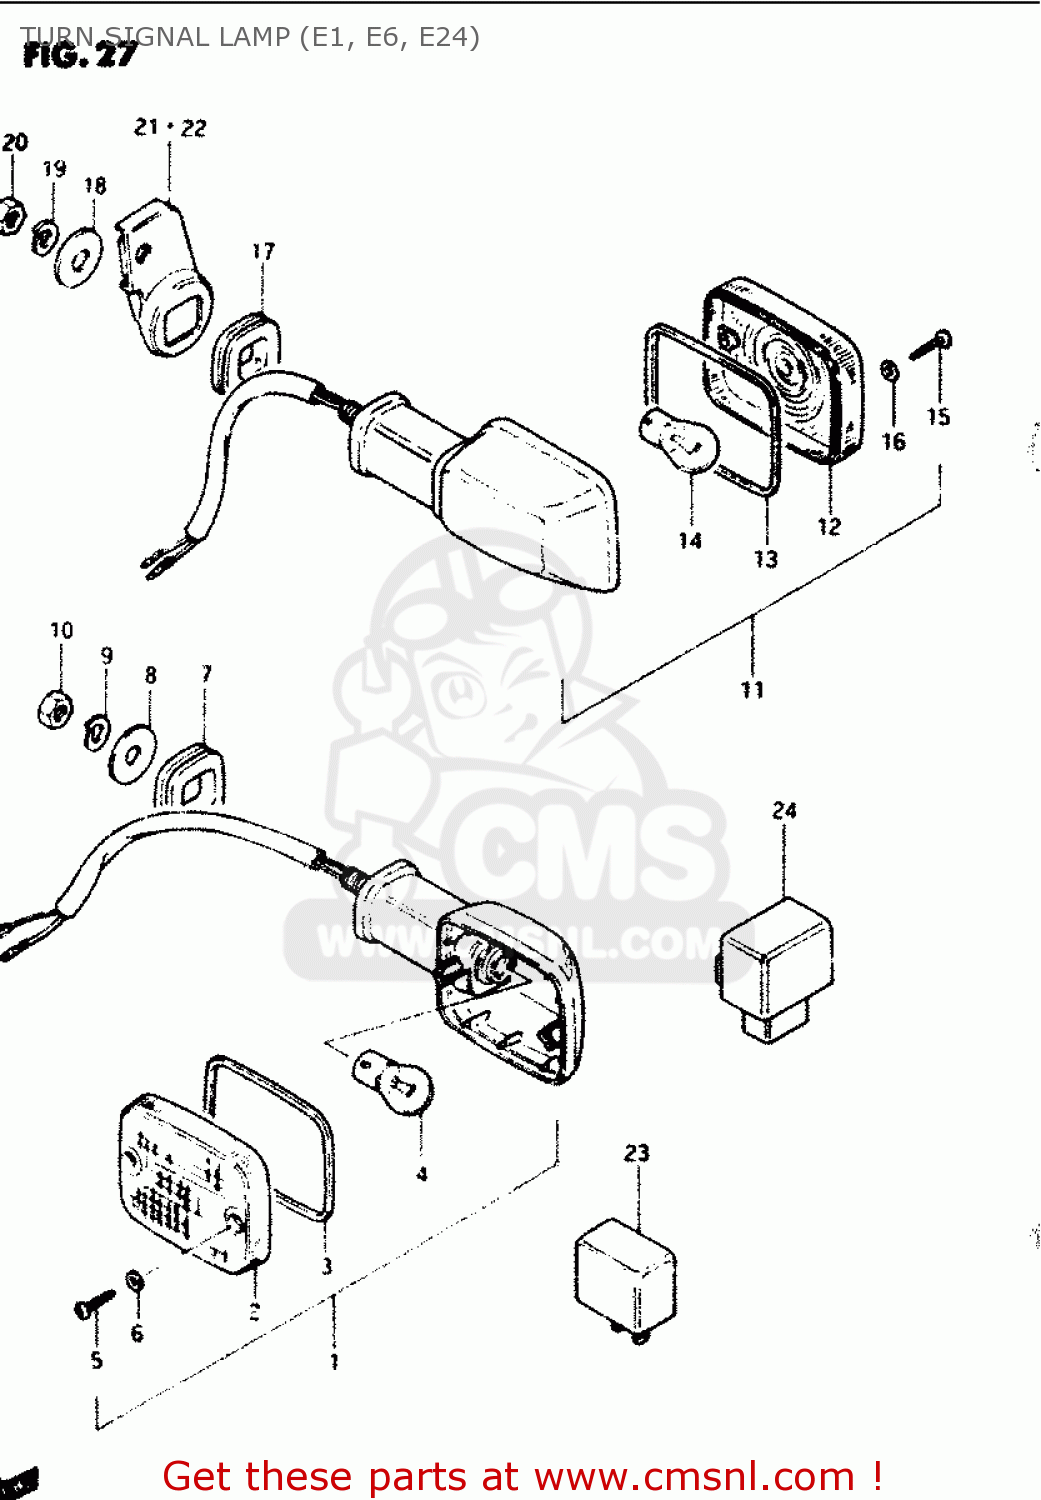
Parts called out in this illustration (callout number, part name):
1	LAMP ASSEMBLY,FRONT TURN SIGNAL
2	LENS
3	GASKET (NAS)
4	BULB(12V23W,STANLEY,A4577A)
5	SCREW
6	GASKET (NAS)
7	CUSHION
8	WASHER (10.5X30X2.3)
9	LOCK WASHER
10	NUT
11	LAMP ASSEMBLY,FRONT TURN SIGNAL
12	LENS
13	GASKET (NAS)
14	BULB(12V23W,STANLEY,A4577A)
15	SCREW
16	GASKET (NAS)
17	CUSHION
18	WASHER (10.5X30X2.3)
19	LOCK WASHER
20	NUT
21	BRACKET,REAR TURN SIGNAL
22	BRACKET,REAR TURN SIGNAL
23	RELAY ASSY,TURNSIGNAL
24	UNIT,TURN SIGNAL CONTROL
